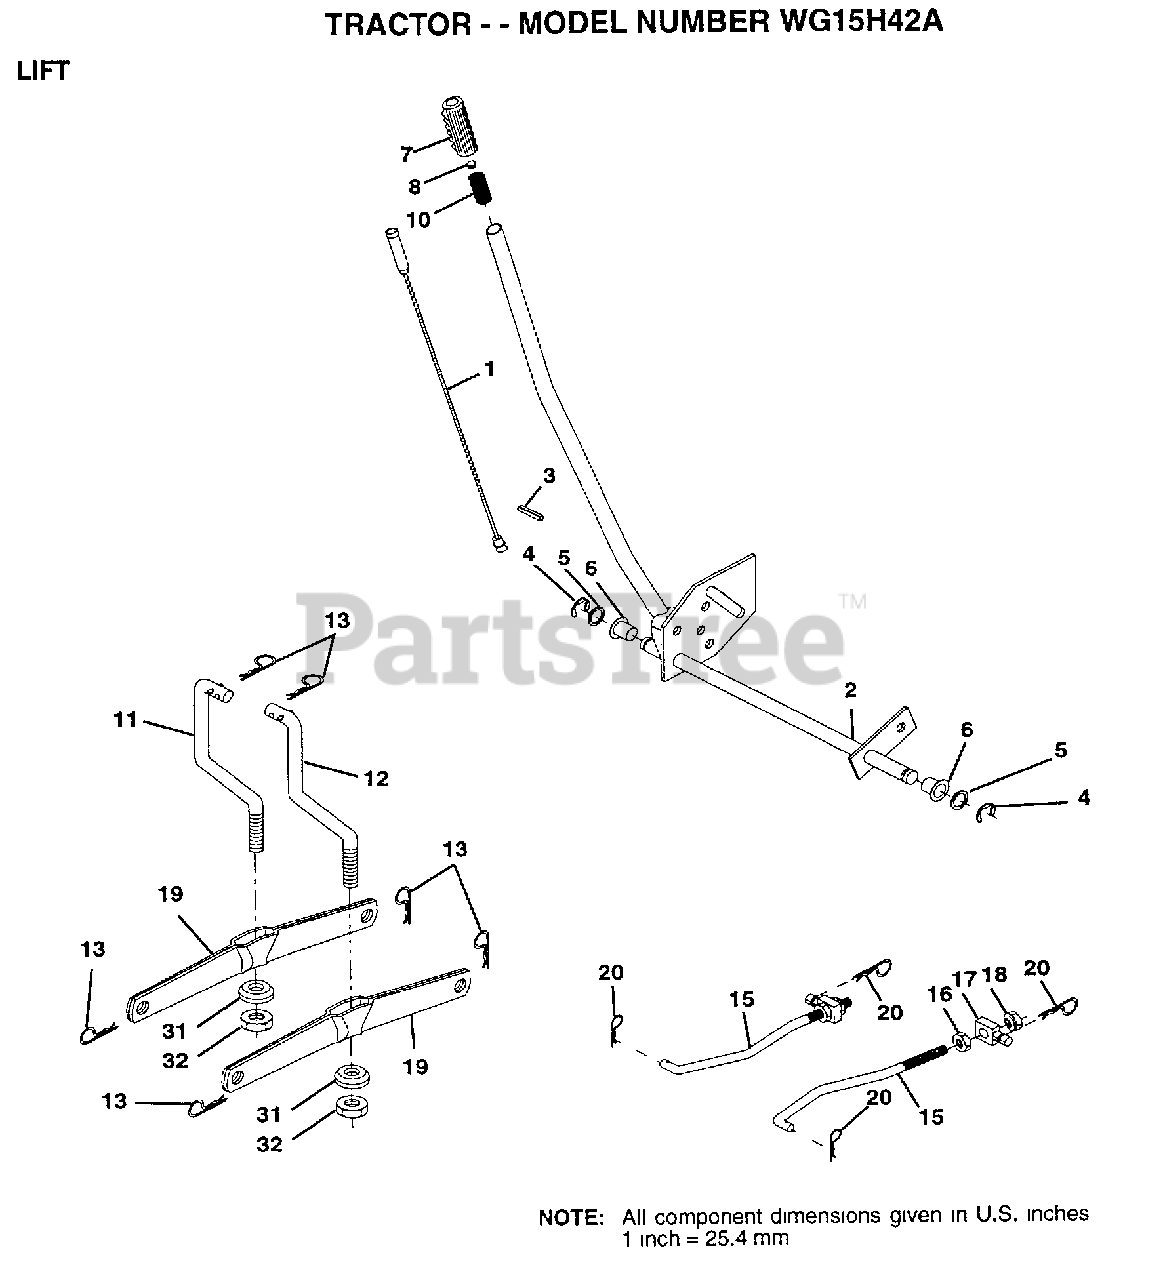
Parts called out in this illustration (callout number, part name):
1	WIRE ASM
2	HANDLE.LIFT.LH.
3	PIN GROOVE
5	WASHER
6	NYLON BEARING
7	GRIP
15	LINK.FRONT
16	NUT
17	TRUNION
18	NUT.LK.W/WSH.1/2.
19	ARM SUSP REAR
20	RETAINER.SPRING
31	BEARING PVT LH
32	NUT.CROWNLOCK.3/8
